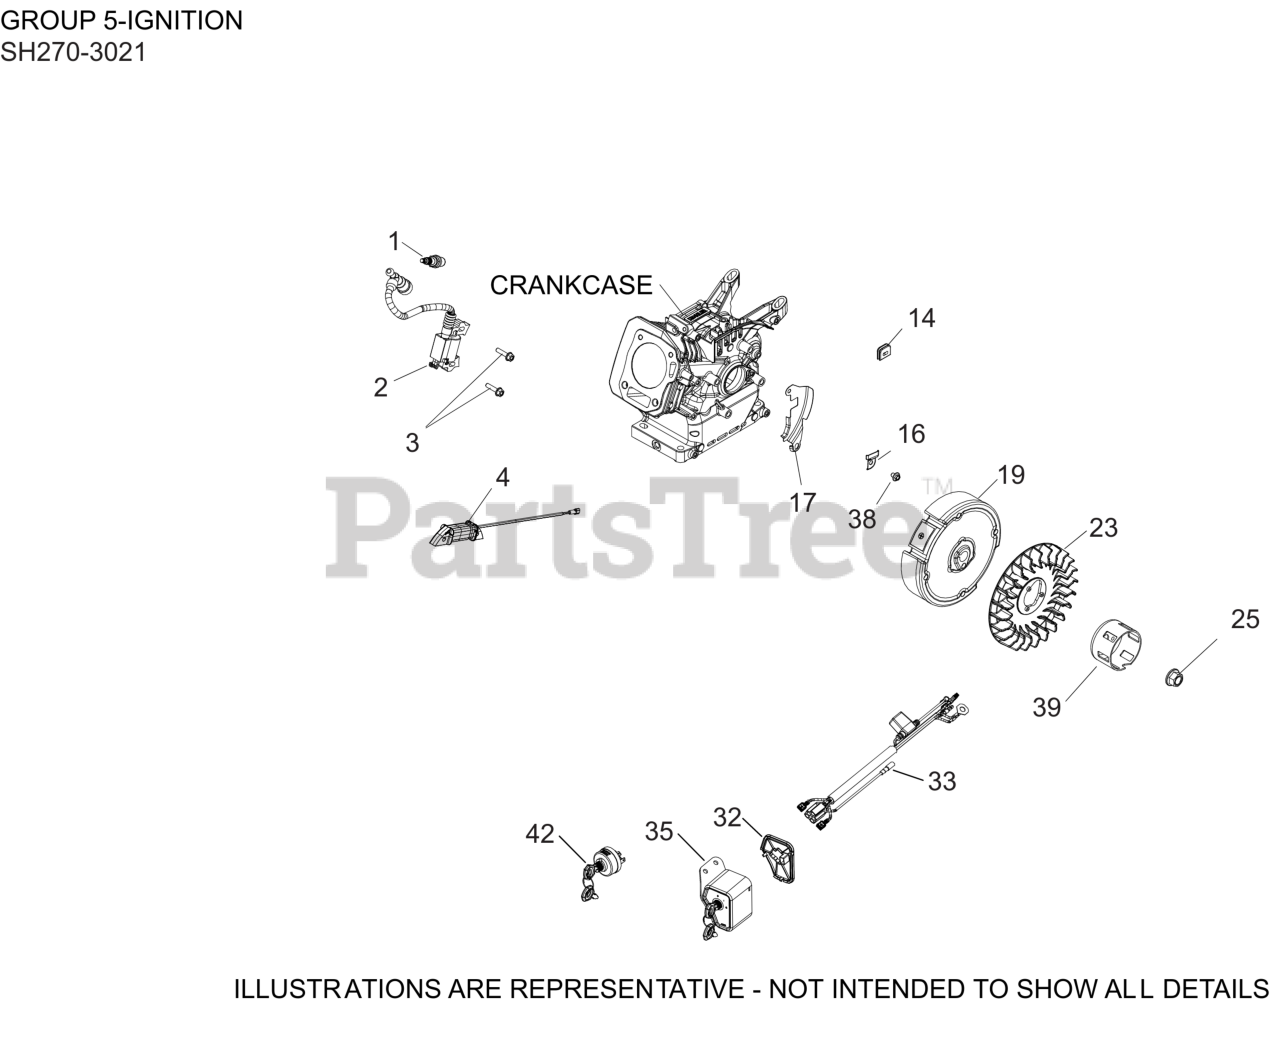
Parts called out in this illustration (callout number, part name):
1	SPARK PLUG
2	MODULE, IGNITION
3	SCREW, M6 X 25-(#25086436S)
4	STATOR ASSEMBLY
14	GROMMET, STATOR WIRE
16	BRACKET, COIL WIRE RETENTION
17	SHIELD, FLYWHEEL ASSEMBLY
19	FLYWHEEL ASSEMBLY - 3 AMP
23	FAN, FLYWHEEL
25	NUT, FLYWHEEL (W/SERRATIONS)
32	COVER, KEY BOX
33	HARNESS, WIRING ASSEMBLY (3 AMP)
35	KIT, KEYBOX HOUSING ASSEMBLY
35	KIT, KEY BOX ASSEMBLY
38	SCREW, M6 X 8
39	STARTER CUP
42	SWITCH, KEY ASSEMBLY
NI	KIT, KEY PLASTIC HANDLE (2 PC)
